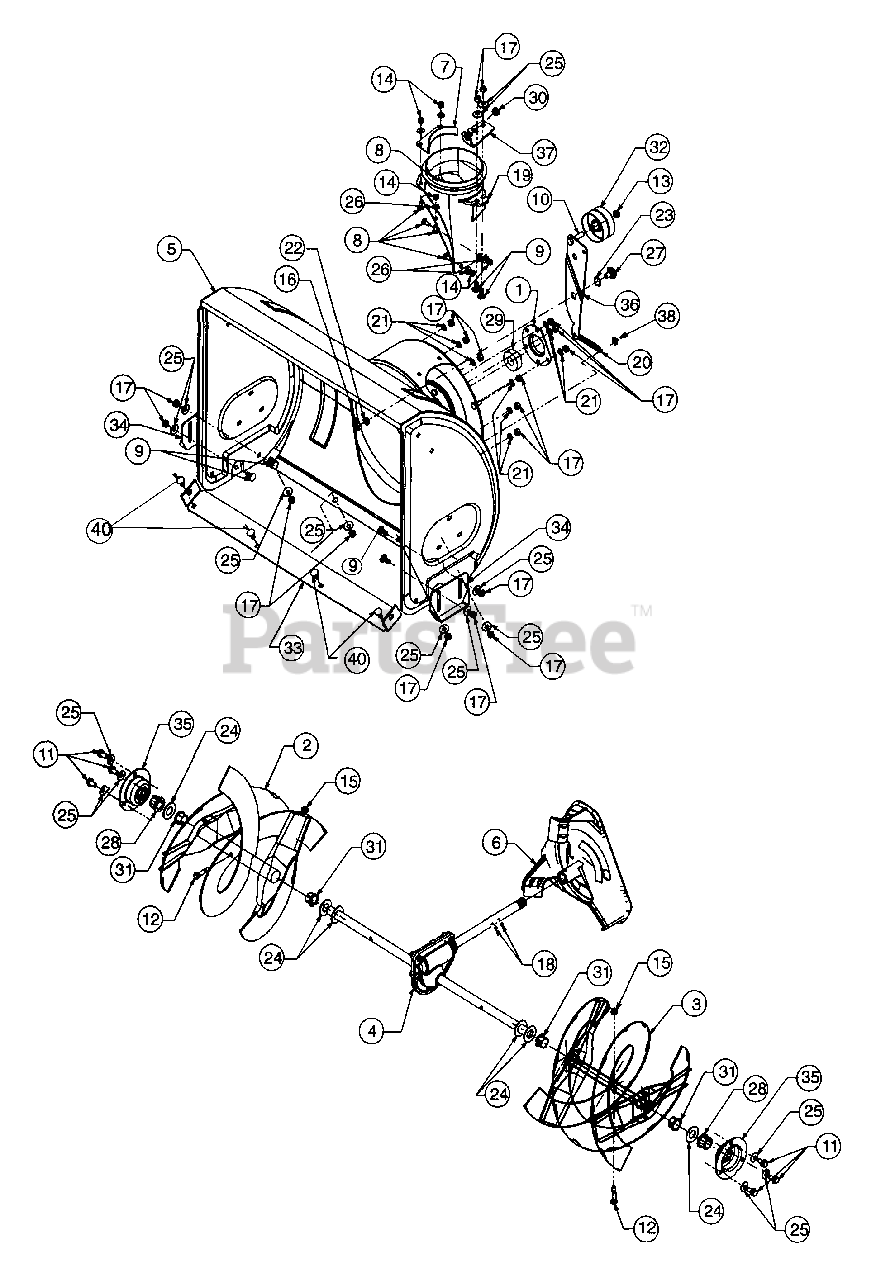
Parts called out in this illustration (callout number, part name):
1	Bearing Housing
8	Carriage Screw 1/4-20 X .75
9	Carriage Bolt 5/16-18 X .75
10	Hex Screw 3/8-24 X 1.5 Grade 5
11	Hex Washer Head TT-Screw 5/16-18 X .62
12	Shear Bolt 5/16-18 X 1.5
13	Jam Lock Nut
14	Toplock Nut 1/4-20
15	Hex Lock Nut 5/16-1B
16	Hex Nut 3/8-16
17	Hex Nut 5/16-18
18	Spiral Pin
19	Chute Adapter
20	Extension Spring
21	Lock Washer 5/16
22	Lock Washer 3/8
23	Wave Washer
24	Flat Washer .76 I.D. x 1.49 O.D.
25	Bell Washer .345 I.D. x.88
26	Flat Washer 1/4 x .630
27	Shoulder Screw
28	Hex Flange Bearing
29	Ball Bearing
30	Plastic Bushing
31	Flange Bushing
32	Flat Idler
38	Patch Nut 5/16-18
40	Carriage Bolt 5/16-18 x .62"
